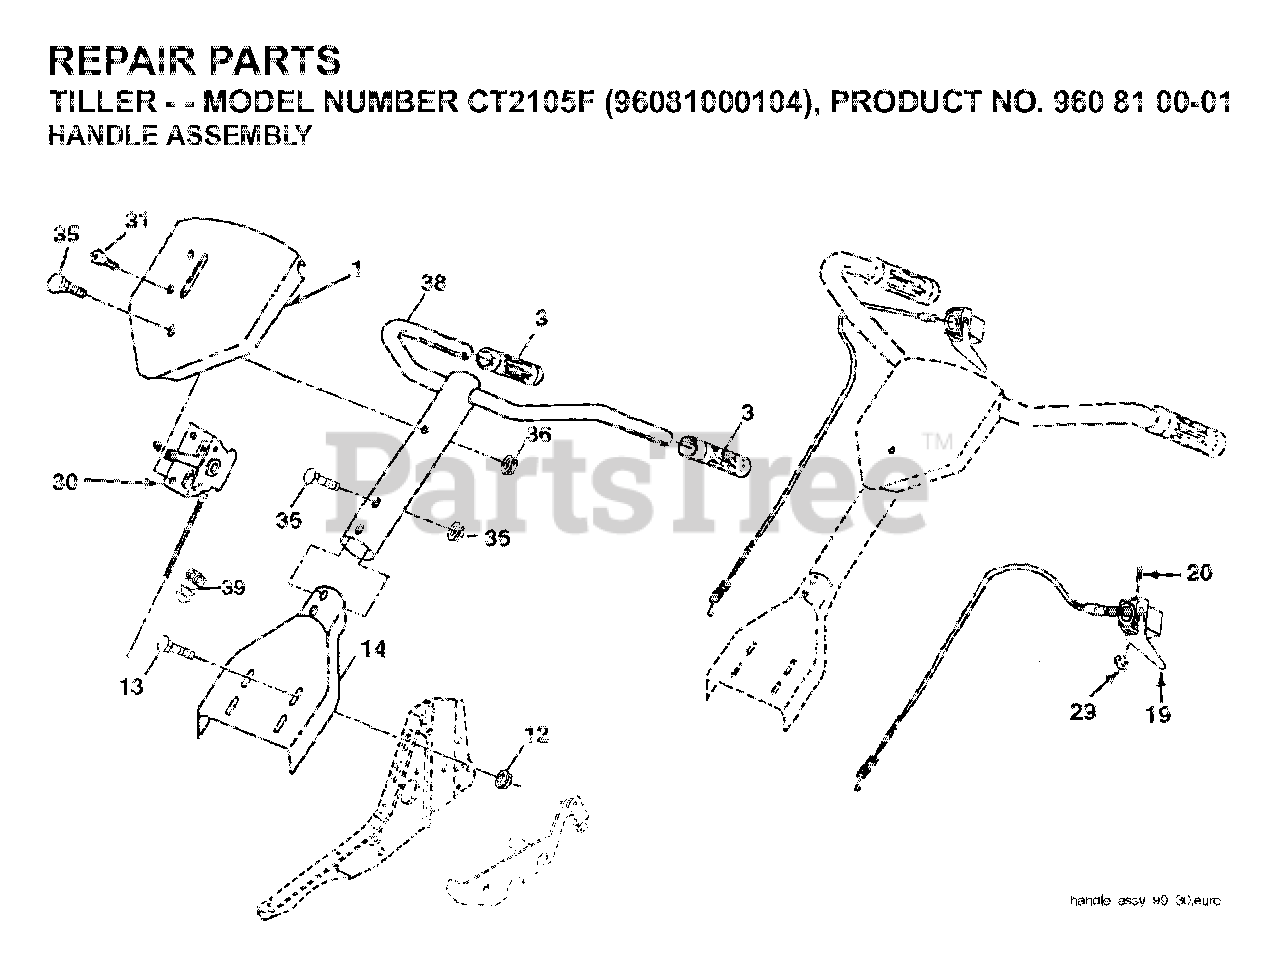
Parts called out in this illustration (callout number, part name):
12	NUT
13	BOLT.RH.SQNK.5/16
14	PANEL ASM. POLE
20	PIN, PIVOT
29	RETAINING RING
31	SCREW
35	BOLT.5/16-18X2.5
36	LOCKNUT-FLANGE 5/16-18
39	CLIP.ROUTING DUAL
